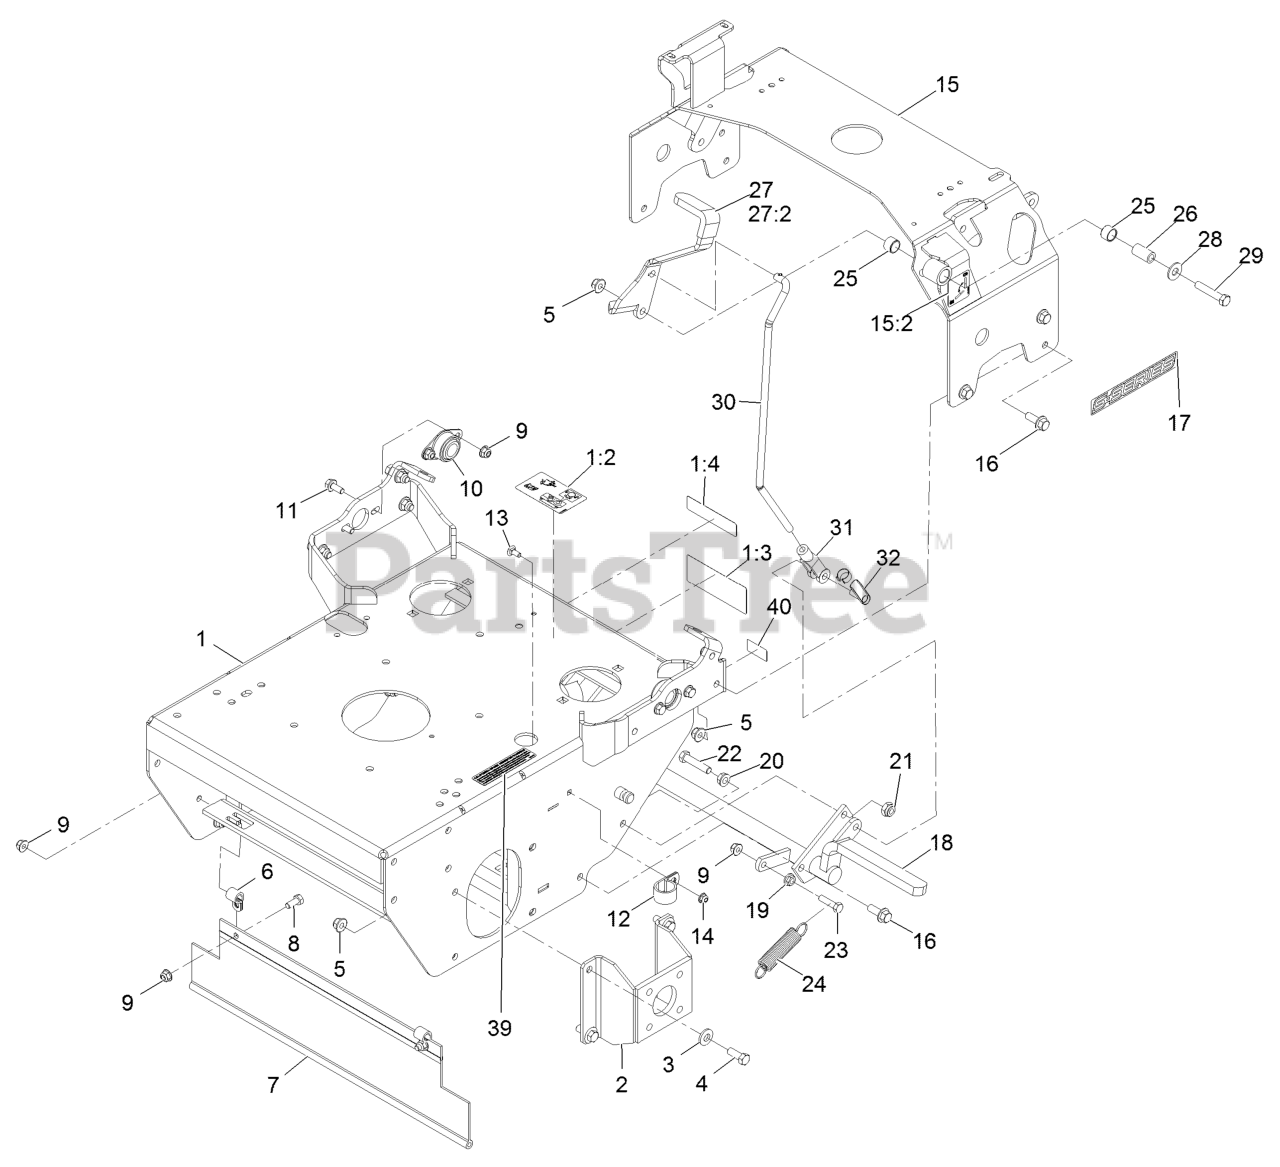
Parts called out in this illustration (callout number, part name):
1	ASM, ENGINE DECK W/ DECAL
1:2	DECAL-DRIVE RELEASE
1:3	DECAL-WARNING, SULKY
1:4	DECAL-WARNING
2	WLD,MOTOR MOUNT 48&52
3	WASHER-BELLEVILLE
4	SCREW-HH
5	NUT-HF, NI
6	CLIP-LOOM
7	SHIELD-DRAG
8	SCREW-HH
9	NUT-HF, NI
10	BEARING-FLANGE, SIDE
11	SCREW-HHF
12	CLIP-LOOM
13	SCREW-CARR
15	ASM, TANK SUPPORT W/ DECA
15:2	DECAL-PARK BRAKE, CE
16	SCREW-HHF 3/8-16 X 1
17	DECAL-S-SERIES
20	NUT-HHF, WHIZ
21	NUT-LOCK, NI
22	SCREW-HH
23	SCREW-HH
24	SPRING-IDLER
25	SLEEVE-BUSHING
26	BUSHING-PIVOT
27	ASM, BRAKE LEVER W/ GRIP
27:2	GRIP-LEVER
28	WASHER-FLAT
29	SCREW-HH
30	LINKAGE, BRAKE
31	YOKE-LINKAGE, BRAKE
32	PIN-SPRING, CLEVIS
39	DECAL-ARRESTER, SPARK
40	Decal-Patent Ttco.Com
